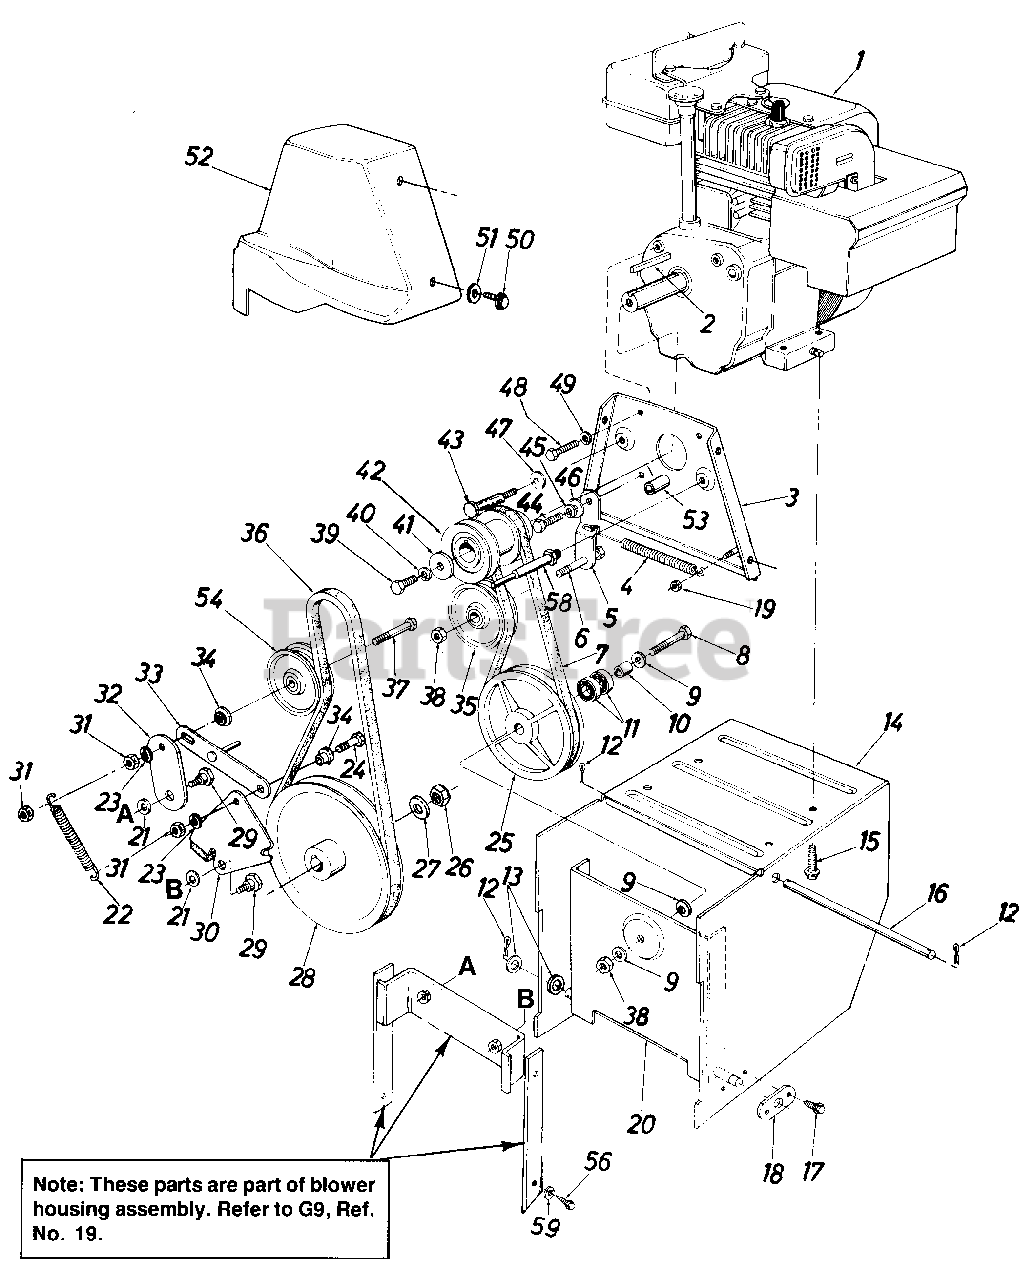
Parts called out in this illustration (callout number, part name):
1	Engine
2	Sq. Key 3/16" x 1.50" Lg. (420 & 524)
3	Engine Plate Ass'y.
4	Extension Spring .50" O.D. x 3.97" Lg.
5	Drive Clutch Idler Brkt.
6	Hex Bolt 3/8-24 x 1.25" Lg.
7	"V"-Belt
8	Hex Bolt 3/8-24 x 1.50" Lg.
9	Bell-Wash. .40" I.D. x .88" O.D. x .06
10	Spacer .38" I.D. x .62" O.D. x.75" Lg.
11	Ball Brg. .62" I.D. x 1.38" O.D. x .44
12	Cotter Pin 3/32" Dia. x .75" Lg.
13	Fl-Wash. .53" I.D. x 1.00" O.D. x .125
14	Frame Ass'y.
15	Hex Wash. Hd. Self-Tap Scr. 3/8-16 x 1.25" Lg.
16	Shaft .50" Dia. x 9.50" Lg.
17	Hex Wash. Hd. Self-Tap Scr. 1/4-20 x .50" Lg.
18	Axle Bracket
19	Hex L-Nut 1/4-20 Thd.
20	Drive Pulley Support Brkt. Ass'y.
21	Bell-Wash. .40" I.D. x 1.13" O.D.
22	Extension Spring .56" O.D. x 4" Lg.
23	L-Wash. 3/8" I.D.
24	Hex Scr. 3/8-16 x 1.25" Lg.
25	6.00" O.D. Drive Pulley Ass'y.
26	Hex Jam Cent. L-Nut 5/8-18 Thd.
27	Fl-Wash. .64" I.D. x .94" O.D. x .06
28	1/2" V-Pulley .625" I.D. x 7.50" O.D. (420 & 524)
29	Shld. Bolt .625" Dia. x .170" Lg. (3/8-1 6)
30	Brake Bracket Ass'y. (420 & 524)
31	Hex Ins. L-Nut 3/8-16 Thd.
32	Auger Clutch Idler Brkt.
33	Brake Linkage Ass'y.
34	Shld. Spacer .625" I.D.
35	Fl-ldler Pulley 2.25" O.D.
36	"V"-Belt (420 & 524)
37	Hex Bolt 3/8-16 x 2" Lg.
38	Hex Ins. Jam L-Nut 3/8-24 Thd.
39	Hex Bolt 3/8-24 x 1.50" Lg.
40	L-Wash. 3/8" I.D.
41	Bell-Wash. .40" I.D. x 1.25" O.D. (420 & 524)
42	Double Groove Engine Pulley (420 & 524)
43	Shld. Scr. .498" x 3.0" Lg. (420 & 524)
44	Hex Bolt 5/16-24 x 1.00" Lg.
45	L-Wash. 5/16" I.D.
46	Shld. Spacer .27" Lg.
47	Bell-Wash. .40" I.D. x .88" x .06
48	Hex Bolt 5/16-24 x .62" Lg.
49	L-Wash. 5/16" I.D.
50	Hex Wash. Hd. Self-Tap Scr. 1/4-20 x .50" Lg.
51	Fl-Wash. .28" I.D. x .75" O.D. x .06
52	Belt Cover
53	Spacer (420 & 524)
54	Fl-ldler Pulley 2.75" O.D.
56	Hex Wash. Hd. Self-Tap Scr. 3/8-16 x .75" Lg.
58	Stud 3/8-16 x 3.37" Lg.
59	L-Wash. 3/8" I.D.-H.D.
